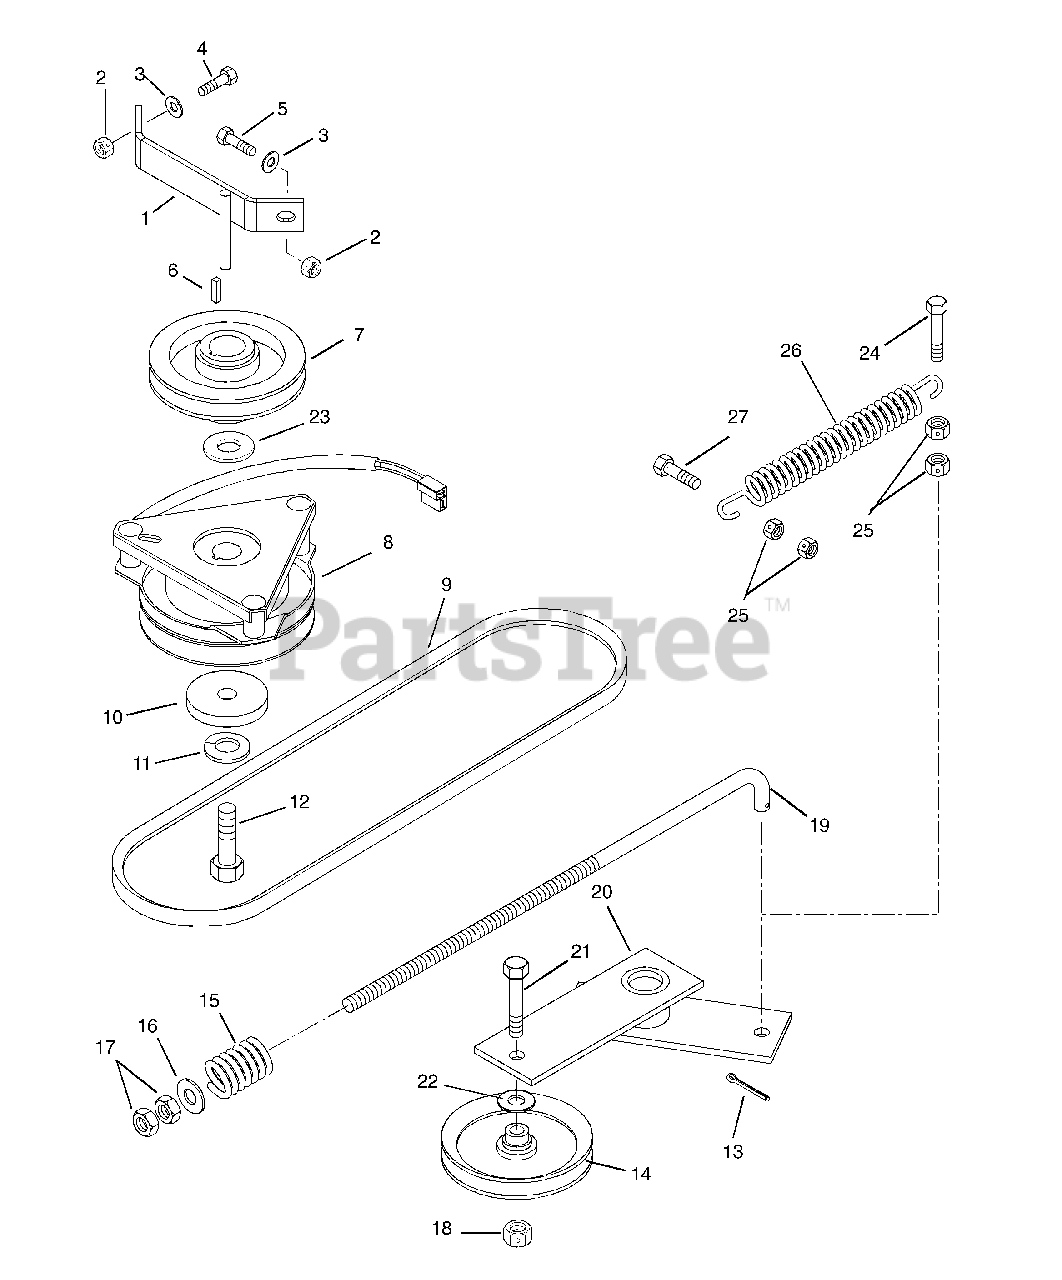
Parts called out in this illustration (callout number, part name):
1	Weldment-PTO Clutch Stop
2	Nut-Locking-Center .31-18
3	Washer-Flat-Steel .344 x .688 x .065
4	Bolt-Hex .31-18 x 1.00 Grade 5
5	Bolt-Hex .31-18 x 1.25 Grade 5
6	Key-Square .248 x 1.25 x .248
8	Clutch-Electric
10	Washer-Special .469 x 2.000 x .250
11	Washer-Locking .44 x 1.09
12	Bolt-Hex .44-20 x 1.75 Grade 5
13	Pin-Cotter .09 x .75
14	Pulley-Idler 4.50 x .380
15	Spring-Compression .072 x .561 x 2.50
16	Washer-Flat-Steel .406 x .812 x .065
17	Nut-Hex .38-16
18	Nut-Locking-Center .38-16
19	Rod-Idler
20	Weldment-Idler
21	Bolt-Hex .38-16 x 1.875
22	Washer-Flat-Steel .39X.75X.175
23	Spacer 1.006 x 1.307 x .500
24	Bolt-Hex .38-16 x 1.50
25	Nut-Lock Center .38-16
26	Spring-Extension
27	Bolt-Hex .38-16 x 2.00 Grade 5
